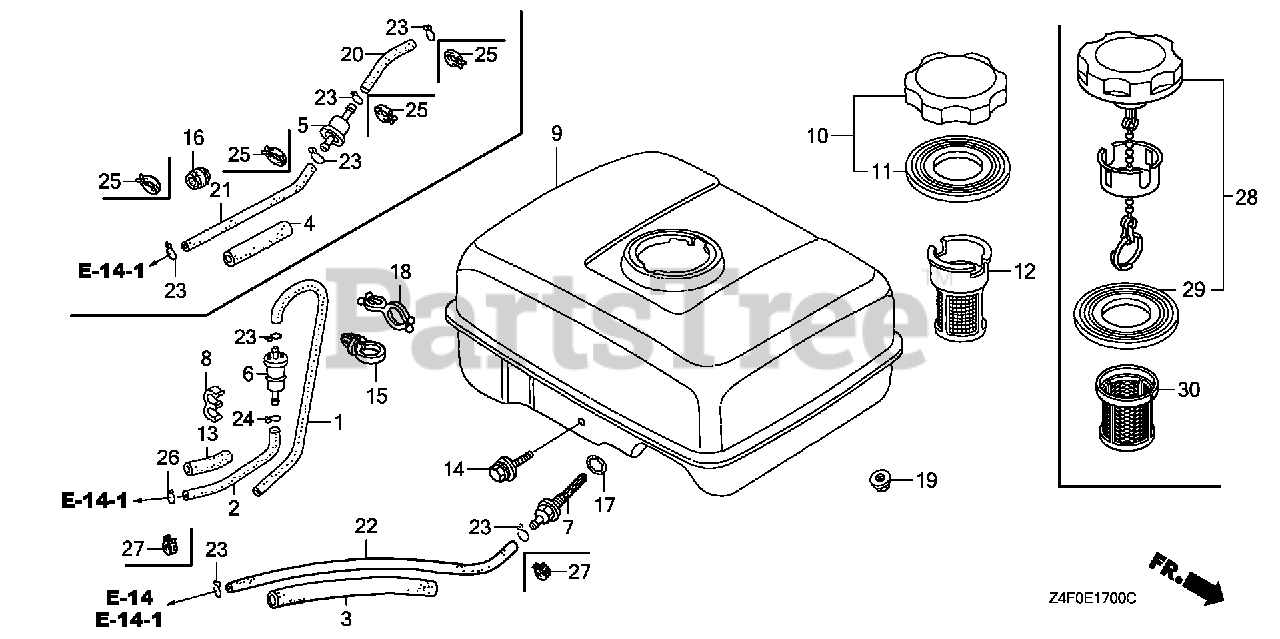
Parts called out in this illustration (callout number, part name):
3	RUBBER, SUPPORTER (107MM)
7	JOINT, FUEL TANK
9	TANK, FUEL *NH31* (MCKINLEY WHITE)
10	CAP, FUEL FILLER (CHROME PLATED)
11	GASKET, FUEL FILLER CAP (39X62X3) (TOUYOUSYA)
12	FILTER, FUEL
14	BOLT, FLANGE (6X29)
17	O-RING (13.5X1.5) (ARAI)
17	O-RING (14MM) (NOK)
19	NUT, FLANGE (6MM)
22	TUBE, FUEL (4.5X140) (FKM)
22	BULK HOSE, FUEL (4.5X3000) (4.5X140)
23	CLIP, TUBE (B8)
27	CLAMP, TUBE (D8)
28	CAP, FUEL FILLER (CHROME PLATED)
28	CAP, FUEL FILLER
29	GASKET, FUEL FILLER CAP (39X62X3) (RADICON)
29	GASKET, FUEL FILLER CAP (39X62X3)
30	FILTER, FUEL
